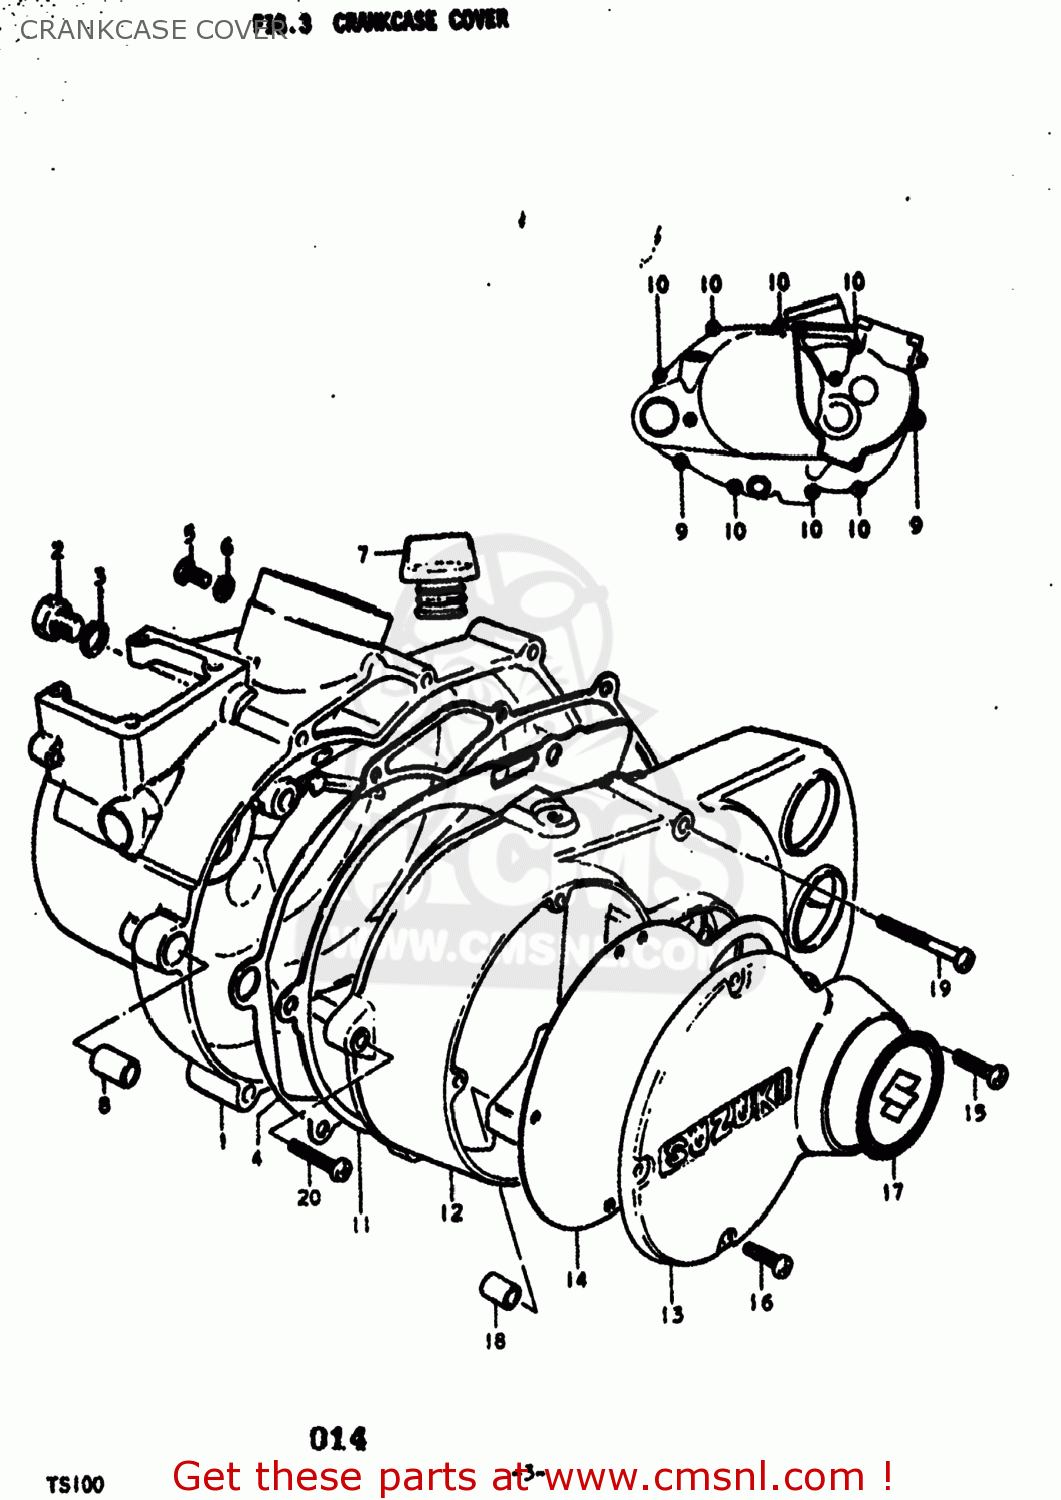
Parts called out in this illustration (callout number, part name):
1	COVER,CLUTCH
2	PLUG
3	GASKET(14X19.2X2) (NAS)
4	GASKET,CLUTCH COVER (MCA)
5	SCREW(6X10)
6	GASKET(6.2X11X1) (NAS)
7	PLUG
8	PIN
9	SCREW
10	SCREW
11	GASKET,MAGNETO COVER (MCA)
12	COVER
13	CAP
14	GASKET (MCA)
15	SCREW
16	SCREW
17	EMBLEM,MAGNETO
18	PIN
19	SCREW
20	SCREW
